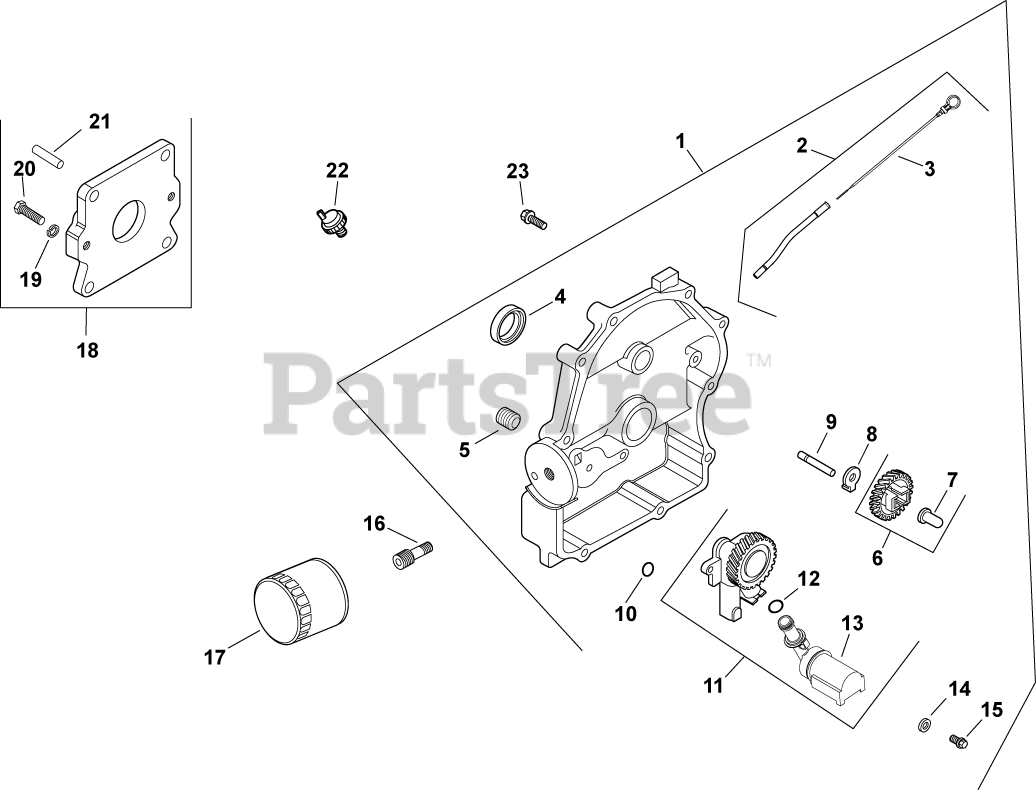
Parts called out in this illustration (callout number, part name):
1	PLATE, CLOSURE & BEARING USE 24 009 227-S
2	KIT, DIPSTICK/DIPSTICK TUBES
4	SEAL, OIL
5	PLUG, CTSK PIPE 1/8"
6	KIT, GOVERNOR GEAR W/PIN
7	PIN, GOVERNOR REGULATING
8	TAB, LOCKING
9	SHAFT, GOVERNOR GEAR
11	PUMP ASSEMBLY, OIL-USE 24 393 53-S
12	O-RING, OIL PICK-UP
13	PICK-UP, OIL
14	SCREW,FLG THD FRM M6X1.0X25-(#25086395S)
15	WASHER, FLAT 6 MM
16	NIPPLE, OIL FILTER
17	OIL FILTER
18	KIT, PUMP ADAPTER
19	WASHER, SPRING LOCK 7/16"
20	SCREW,CAP HD 7/16-14x1 1/2"
21	PIN, ALIGNMENT
22	SENSOR, OIL PSI
23	SCREW, FLG M8X1.25X45
